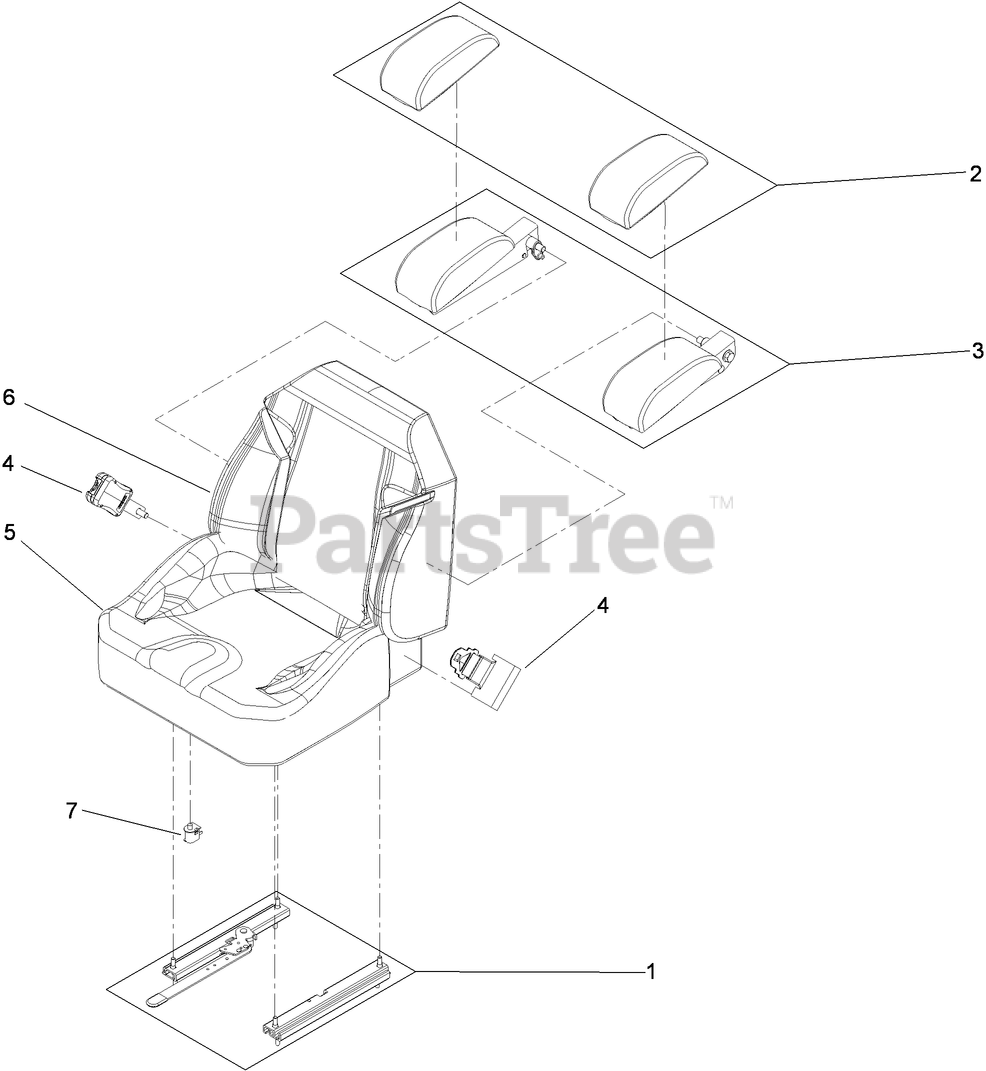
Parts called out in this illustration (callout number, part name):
1	SEAT TRACK SET
2	ARM REST PAD SET
3	ARM REST SET
4	SEAT BELT KIT
5	COVER-CUSHION
6	COVER-BACK
7	SWITCH-BAIL
